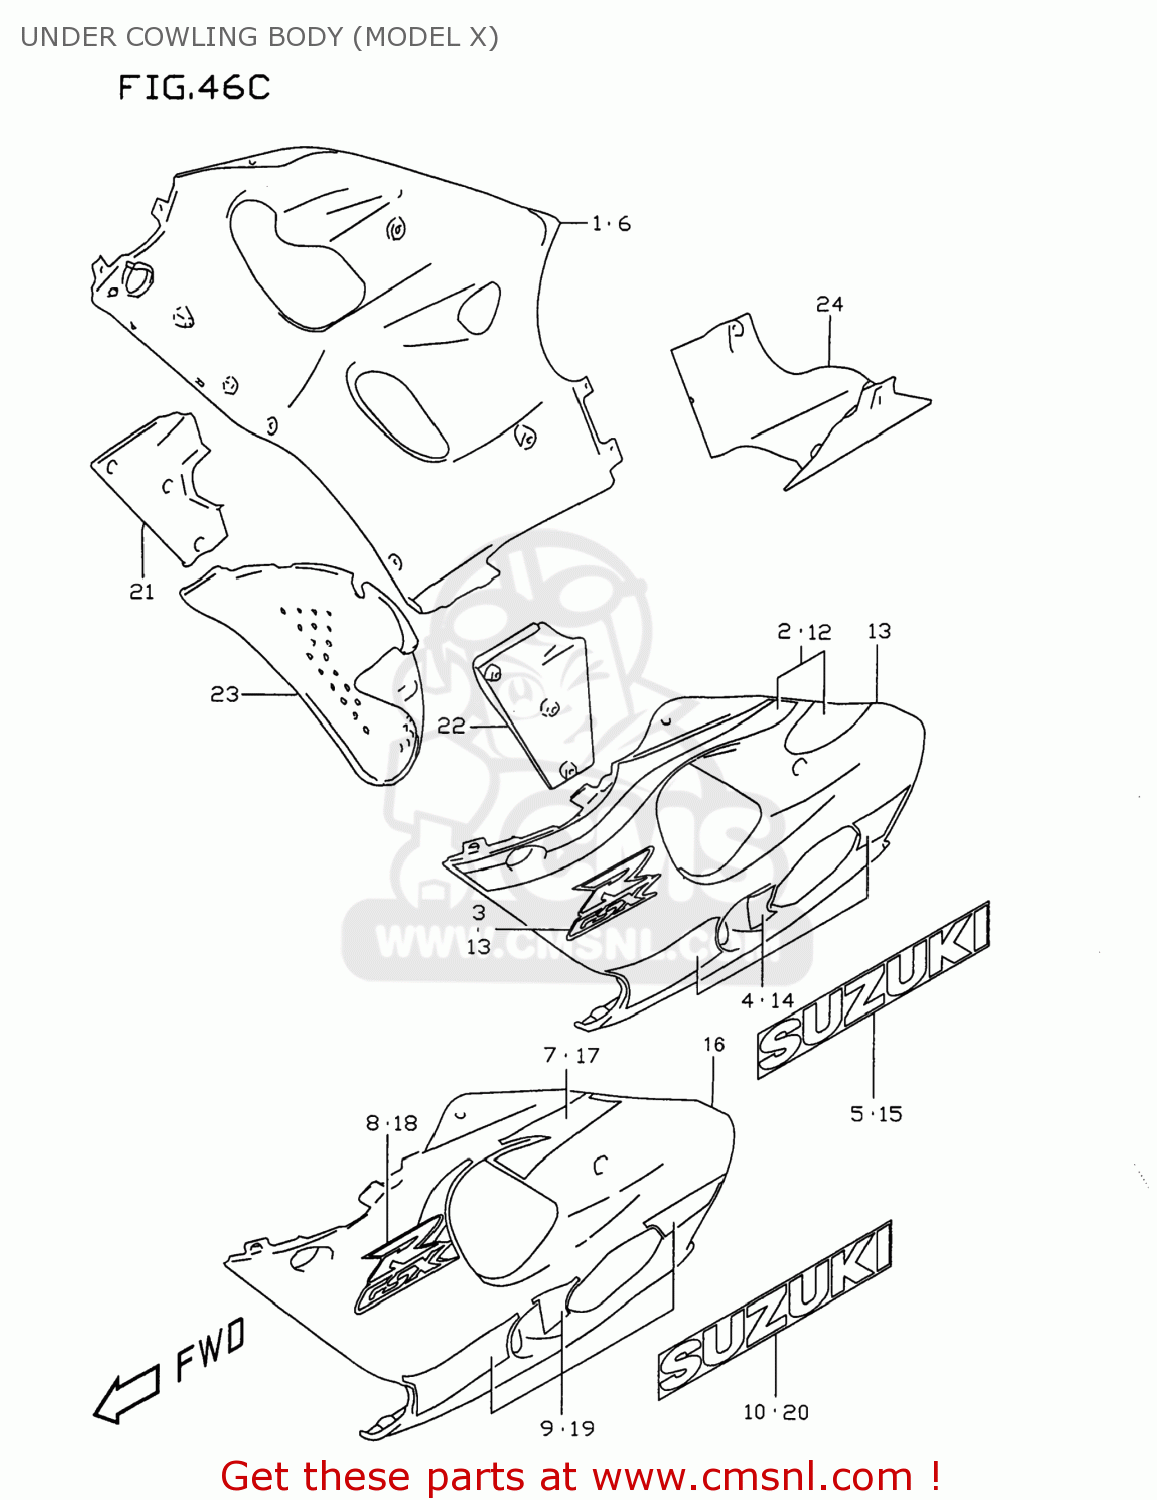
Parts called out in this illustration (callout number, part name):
1	COWLING ASSEMBLY,UNDER,RIGHT
2	TAPE SET,COWL UNDER,R
3	EMBLEM,GSXR
4	TAPE SET,R
5	EMBLEM,SUZUKI
6	COWLING ASSEMBLY,UNDER,RIGHT
7	TAPE,COWL UNDER UPR,R
8	EMBLEM,COWLING UNDER,R
9	TAPE SET,COWL UNDER LWR,R
10	EMBLEM,SUZUKI(SILVER)
11	COWLING ASSEMBLY,UNDER,LEFT
12	TAPE SET,COWL UNDER,R
13	EMBLEM,GSXR
14	TAPE SET,L
15	EMBLEM,SUZUKI
16	COWLING ASSEMBLY,UNDER,LEFT
17	TAPE,COWL UNDER UPR,L
18	EMBLEM,COWLING UNDER,L
19	TAPE SET,COWLING,UNDER,LOWER
20	EMBLEM,SUZUKI(SILVER)
21	COWLING,UNDER INNER,R
22	COWLING,UNDER INNER,L
23	COWLING,UNDER CTR
24	COWLING ASSEMBLY,UNDER,REAR
